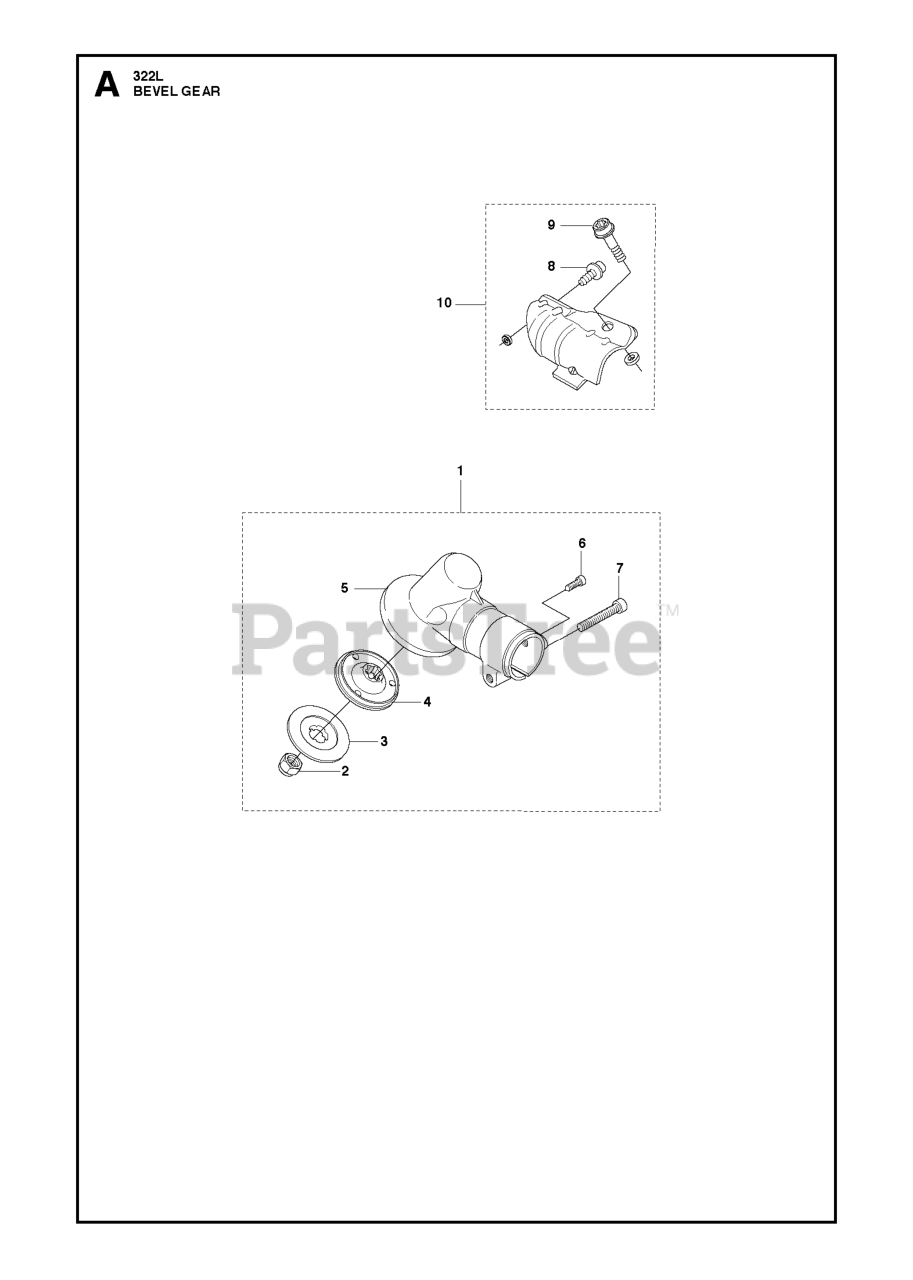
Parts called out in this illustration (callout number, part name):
1	GEAR HEAD ASSY W/ HOLDER & NUT
2	GEARHEAD NUT - BRUSHCUTTER
3	SUPPORT FLANGE
4	DRIVE DISC
5	GEAR HEAD ASSY
10	ASSY CLAMP 523L
